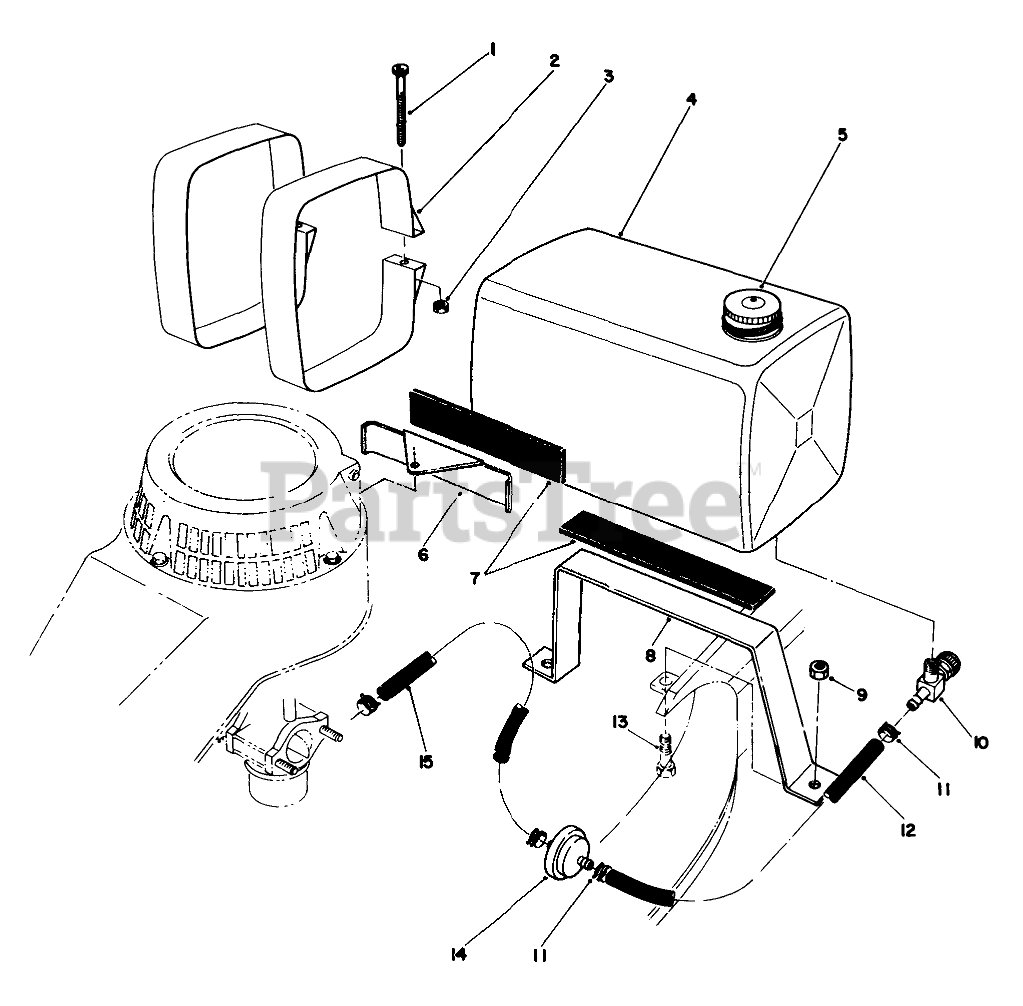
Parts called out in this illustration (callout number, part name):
1	SCREW-HSH
2	TANK STRAP WA
3	NUT-HEX
4	Tank-Gas (Incl. Ref. #5)
5	GAS CAP
6	FRT TANK MOUNT
7	ISOLATOR PAD
8	TANK BOTTOM MOUNT
9	NUT-LOCK, NI
10	.125 ID SHUTOFF VALVE
11	CLAMP-FUEL LINE
12	LINE-GAS
13	SCREW-HH
14	FILTER-FUEL
15	HOSE-FUEL
